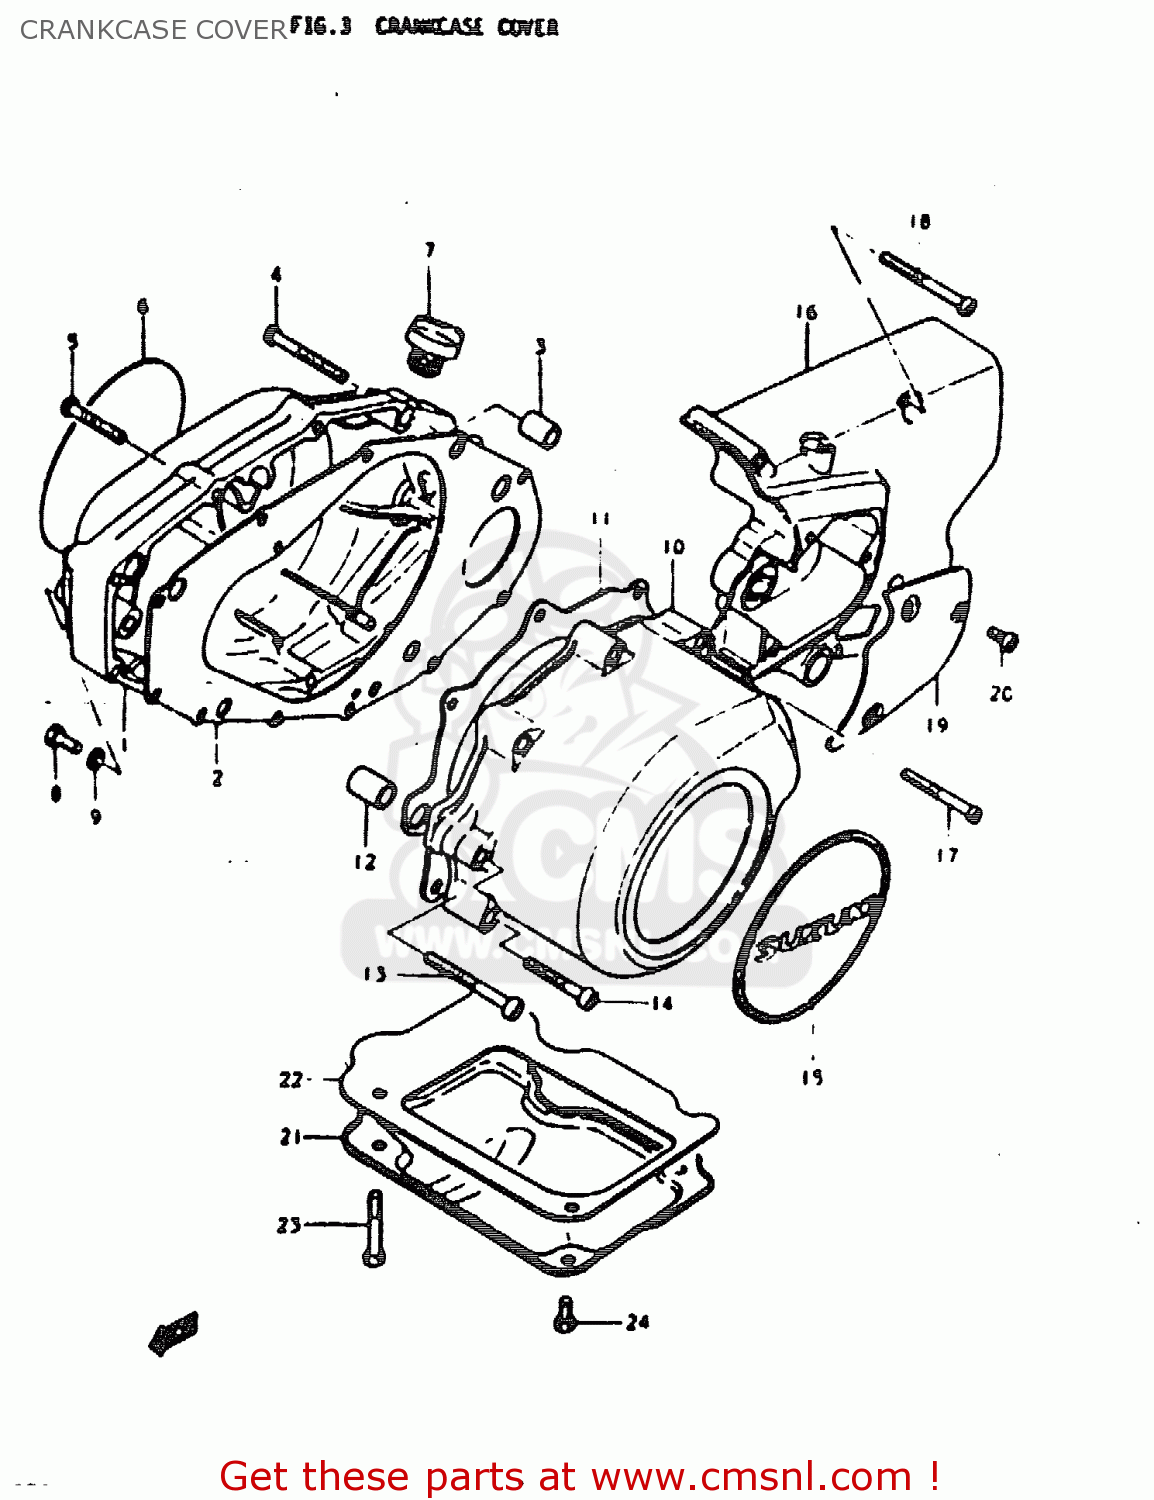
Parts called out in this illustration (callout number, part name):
1	COVER, CLUTCH
2	GASKET, CLUTCH COVER (MCA)
3	PIN
4	SCREW
5	SCREW (6X35)
6	EMBLEM,COVER
7	PLUG
8	SCREW(6X10)
9	GASKET(6.2X11X1) (NAS)
10	COVER, MAGNETO
11	GASKET (MCA)
12	PIN
13	SCREW
14	SCREW (6X35)
15	EMBLEM,COVER
16	COVER, ENGINE SPROCKET
17	SCREW (6X45)
18	SCREW
19	CAP, RELEASE ADJUSTO
20	SCREW
21	COVER,STARTER MOTOR
22	GASKET,STARTER (MCA)
23	BOLT
24	BOLT(6X8)
